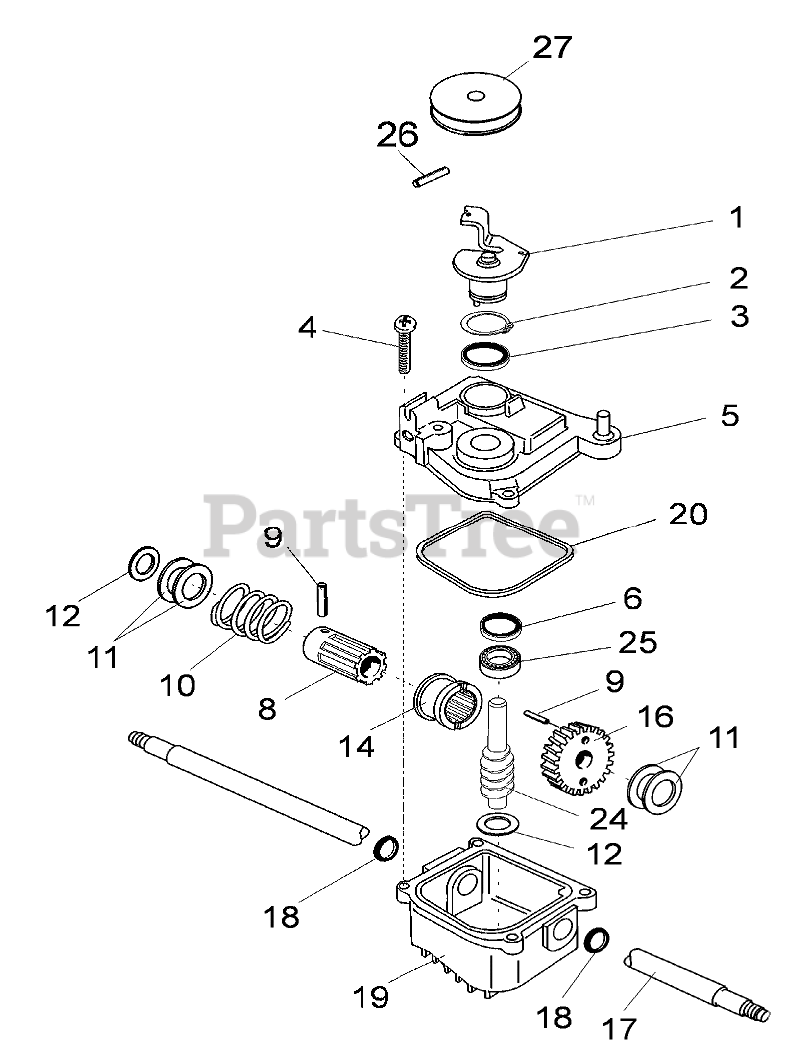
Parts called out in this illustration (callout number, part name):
2	Snap ring
5	Housing-Upper
8	Driver
10	Spring
12	Washer
14	Sleeve-Clutch
19	Housing-Bottom
20	Gasket-Gearbox
24	GEAR-WORM
25	Bearing
26	Pin-Roll
27	PULLEY-GEARBOX
